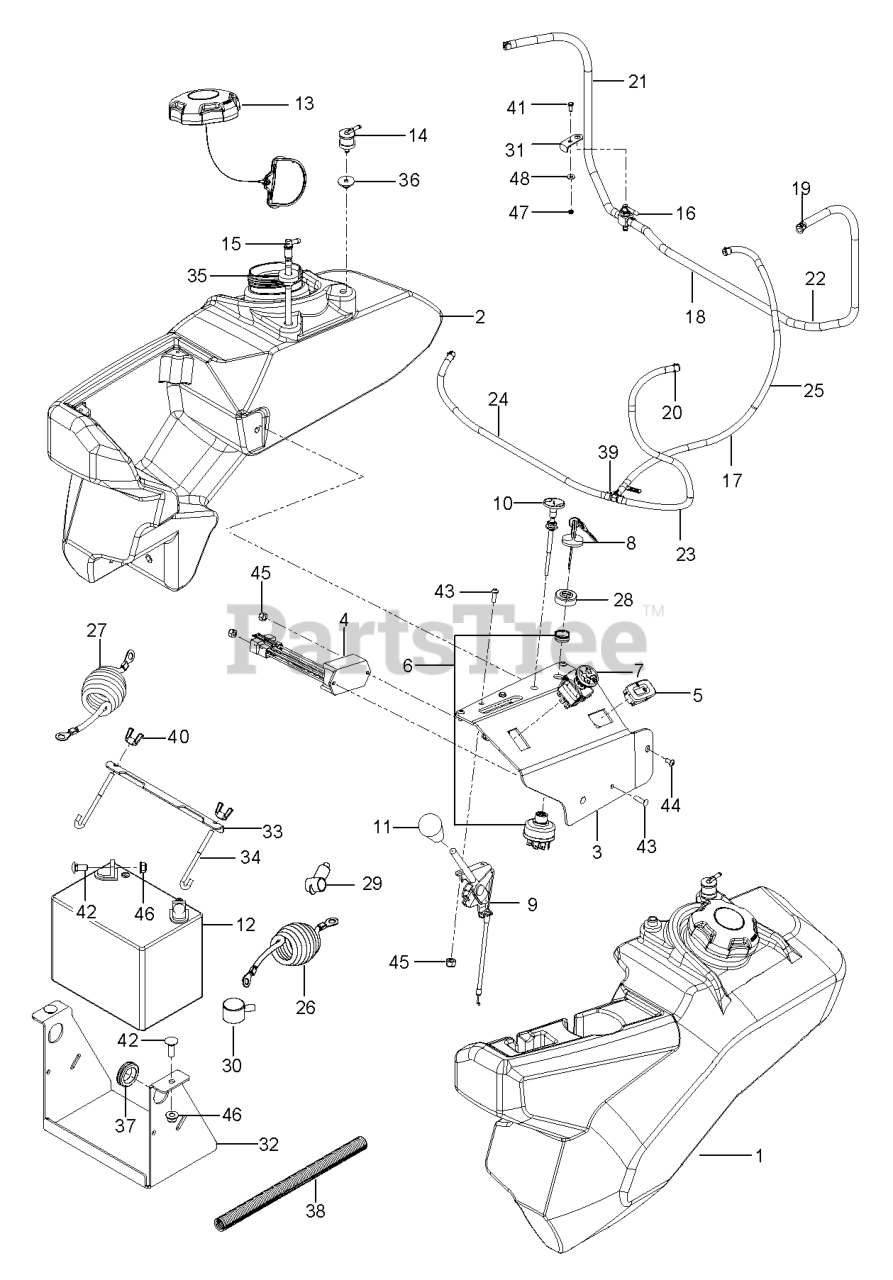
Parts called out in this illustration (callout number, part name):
1	FUEL.TANK.ASM.LH.PZ.BLACK.18
2	FUEL TANK ASSY RH. PZ. BLACK.
3	PANEL, CONTROL GAS BLACK
4	TIMER, SEAT
5	GUAGE.SRVCMNDR.HRMTR.
6	SWITCH, IGNITION, INDAK
7	RP SWITCH.PTO.TERMINAL.STD.RED
8	KEY, IGNITION
9	CABLE, THROTTLE, 60"
10	CABLE, CHOKE, 48"
11	KNOB - SHIFT
12	BATTERY WET NOT SELLABLE
13	CAP 3.5IN SEALED
14	VALVE.FUEL.CHECK
15	FITTING, FUEL
16	FUEL VALVE
17	HOSE.ASM.VAPOR.LINE.21-30-39
18	ASSEMBLY, FUEL LINE
19	HOSE CLAMP
20	CLAMP, HOSE
21	HOSE.1/4".LOW.PERM.FUEL.LN.22"
22	HOSE.1/4".LOW.PERM.FUEL.LN.38"
24	HOSE.3/16".VAPOR.LINE.21"LGTH
25	HOSE.3/16".VAPOR.LINE.30"LGTH
26	CABLE, POSITIVE, 55"
27	CABLE, NEG, 55"
28	CAP IGNITION NUT
29	INSULATOR
30	ROD.BYPASS.VARIATOR.GEN2
31	BRACKET.VALVE.PNT.BLACK.X431
32	BRACKET, BATTERY, BLK
33	Brackets
34	HOOK, "J"
35	RUBBER GROMMET
36	VALVE.FUEL.CHECK
37	RUBBER GROMMET
38	LOOM SPLIT 5/8, 32"
39	TEE, FUEL LINE 3/16"
40	WING NUT 1/4
41	HCS 1/4C X 3/4 HCS
42	BOLT 5/16-18 X3/4 ZN/YEL GR 5
43	SCR #10-24 X .75 SKT HD BLK
44	SCR #10-24 X 3/8 SKT HD BLK OX
45	NUT 10-24 NYLOC
46	5/16-18 NYLOC FLANGE NUT
47	JAM NUT 1/4C (2 2 PW01)
48	WASHER 1/4 FLAT
